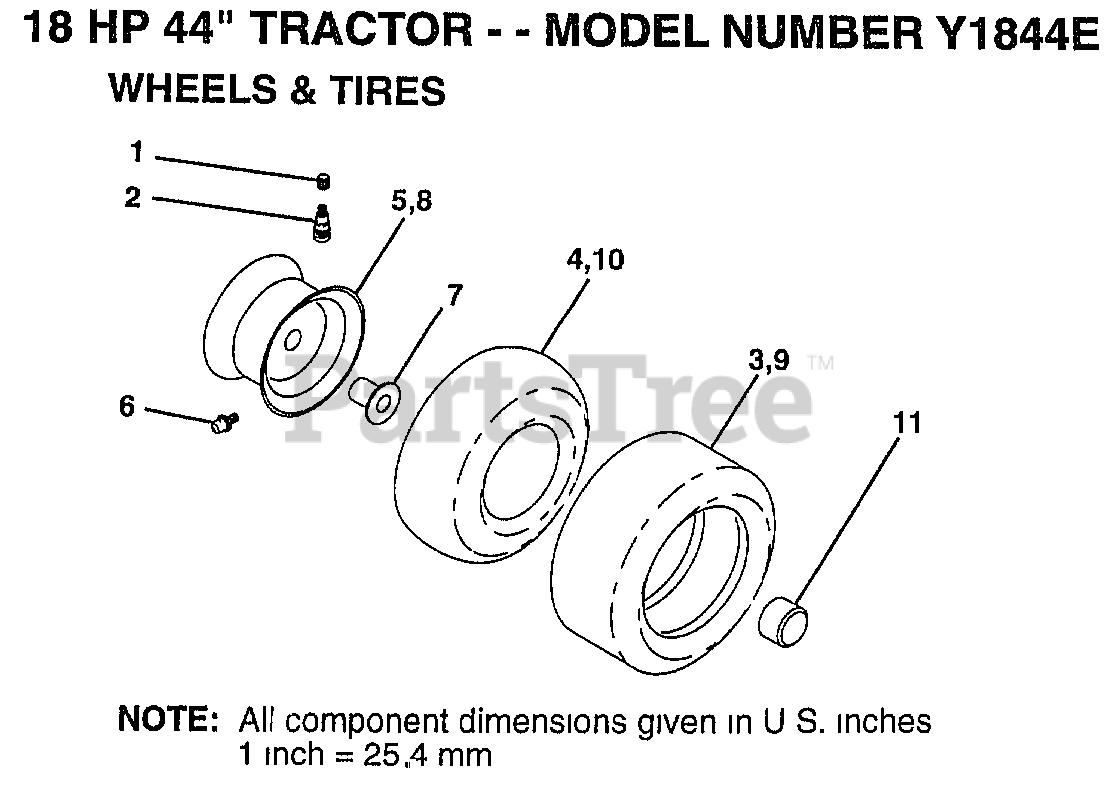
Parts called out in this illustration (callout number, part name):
1	VALVE CAP
2	VALVE STEM LT
4	TUBE.5.3/4.5/6
5	RIM.FRONT.
6	FITTING LT
7	"FLANGE, BEARING"
8	RIM.REAR.417
9	TIRE.R.23X9.5-12
10	TUBE.23X8/10-12
11	HUB CAP
